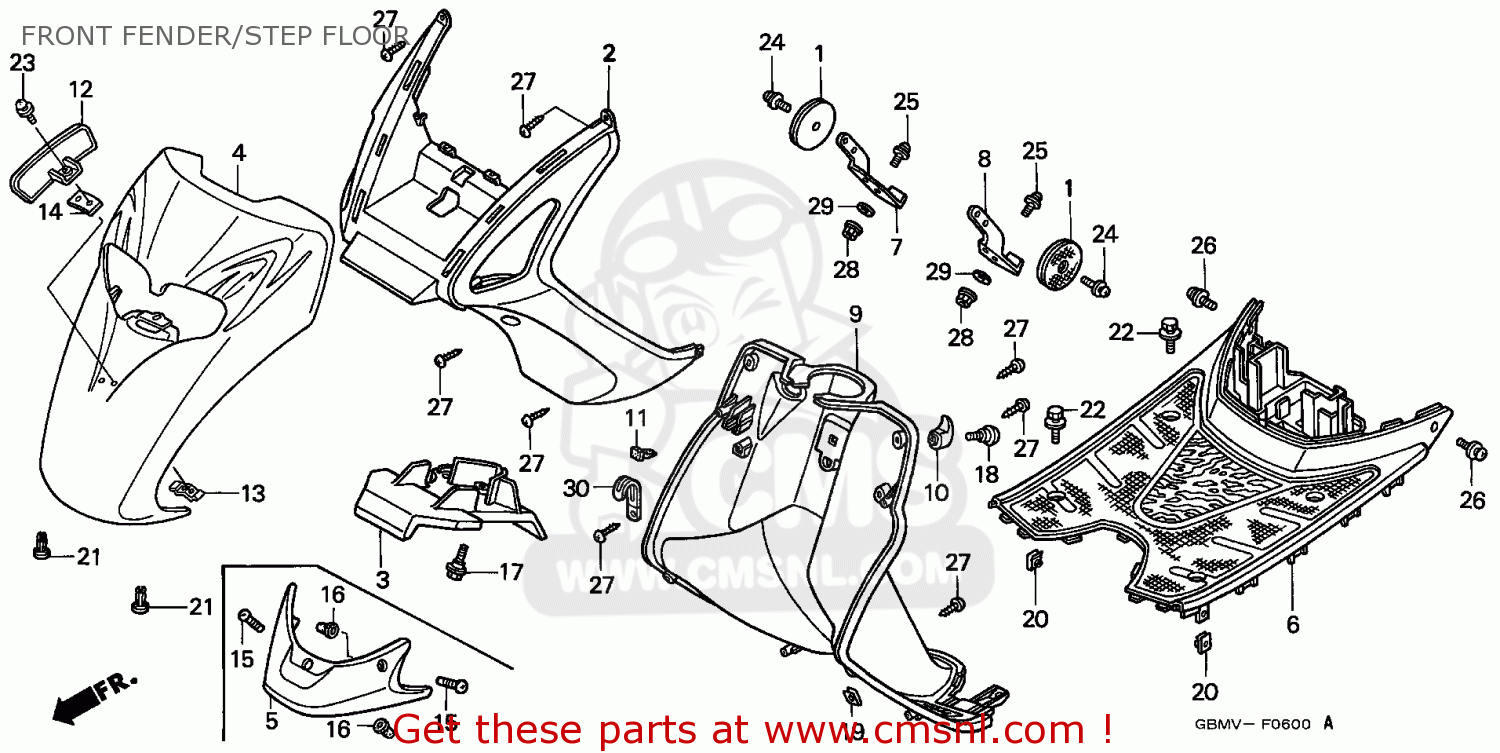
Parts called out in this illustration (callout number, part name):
2	FENDER FRONT NH1
3	FENDER FR. INNER
4	SET ILLUST*TYPE1*
6	PANEL FLOOR NH1
9	COVER INNER NH1
10	HOOK,LUGGAGE*NH1*
11	STOPPER,LUGGAGE
17	BOLT,SPECIAL,5MM
18	SCREW,SPECIAL,6MM
19	NUT,SPRING,5MM
20	NUT,CLIP 5MM
21	CLIP,TRIM
22	BOLT-WASHER,6X25
26	SCREW-WASH 5X12
27	SCREW,4X12
30	CLIP,WIRE
